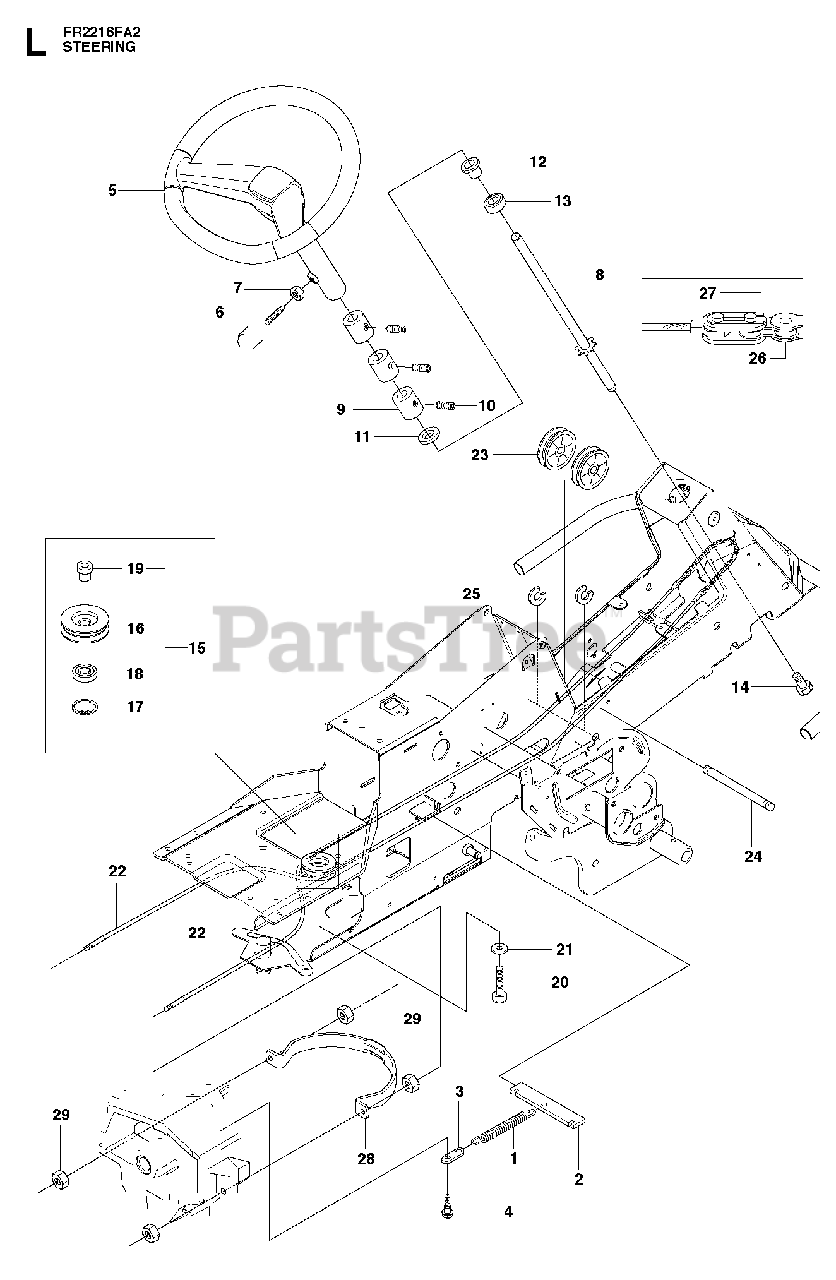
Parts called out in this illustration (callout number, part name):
2	SPRING BRACKET
3	CONNECTOR
5	STEERING WHEEL
7	NUT
8	ROD STEERING ASSY
13	BALL BEARING 6004-2RS1
16	ROLLER
17	CIRCLIP SGH 47
18	BALL-BEARING 6204-2RS
19	BUSHING
20	COLLAR SCREW
22	RP STEERING CABLE COMPLETE
25	RETAINING RING
26	STEERING CHAIN
28	WIRE GUIDE
